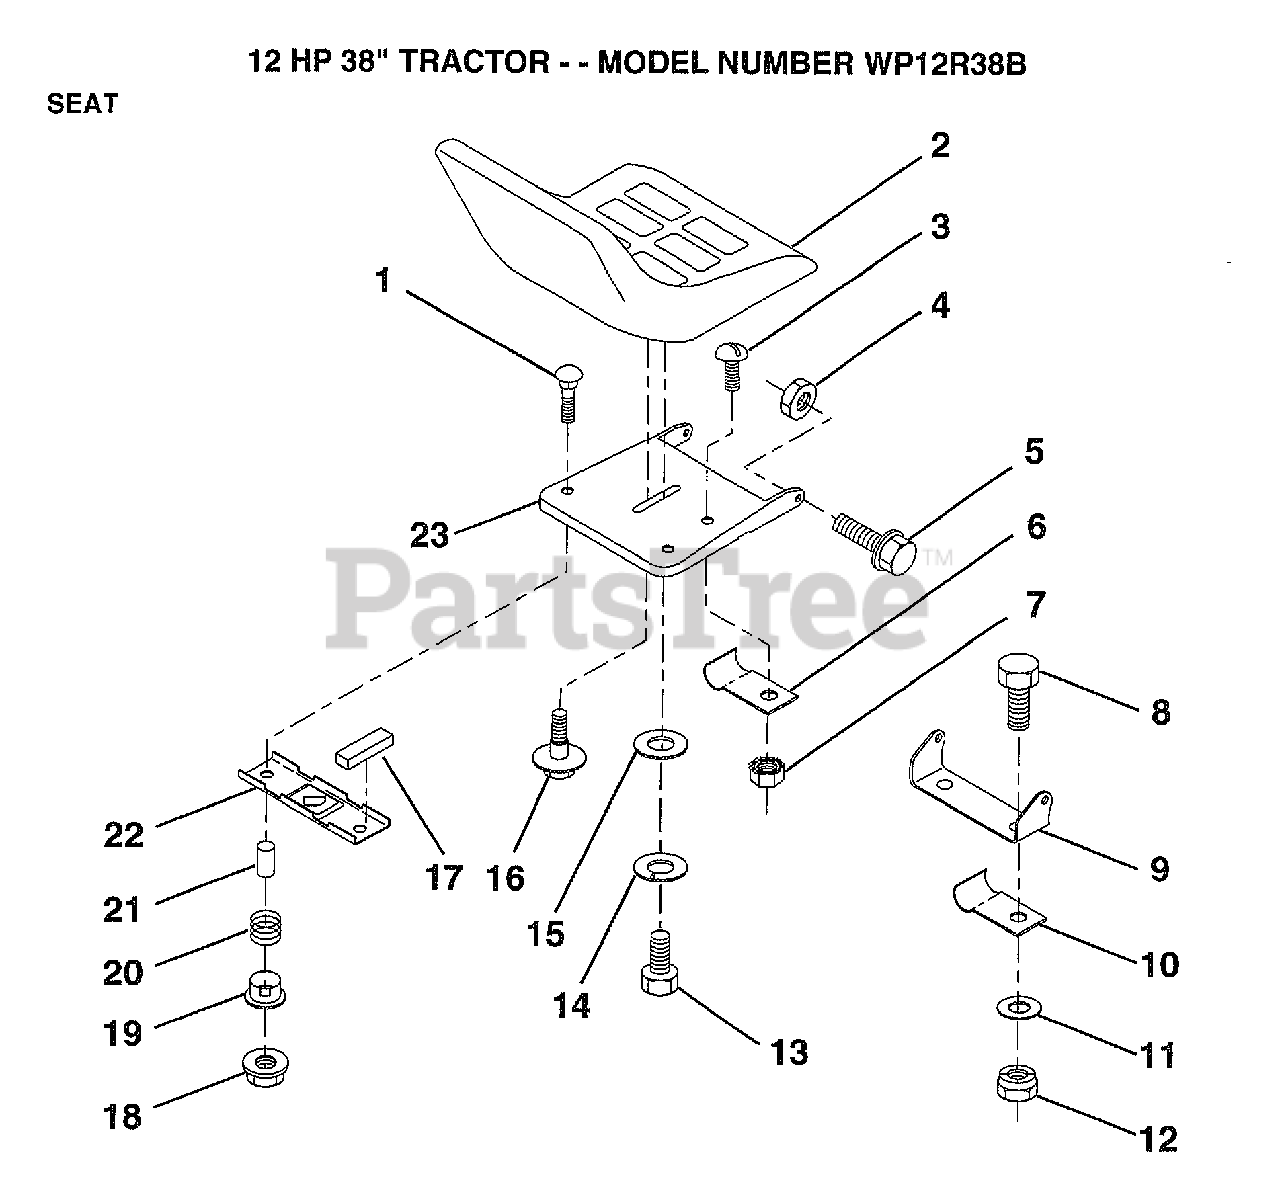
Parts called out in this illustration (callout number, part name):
7	"NUT,KEPS"
10	"CLIP,INSULATOR"
11	WASHER
13	BOLT
14	LOCKWASHER
15	WASHER
16	"BOLT,SHOULDER"
17	STRIP FORM
19	BUSHING
20	SPRING
21	SPLIT SPACER
22	BRKT SWITCH
